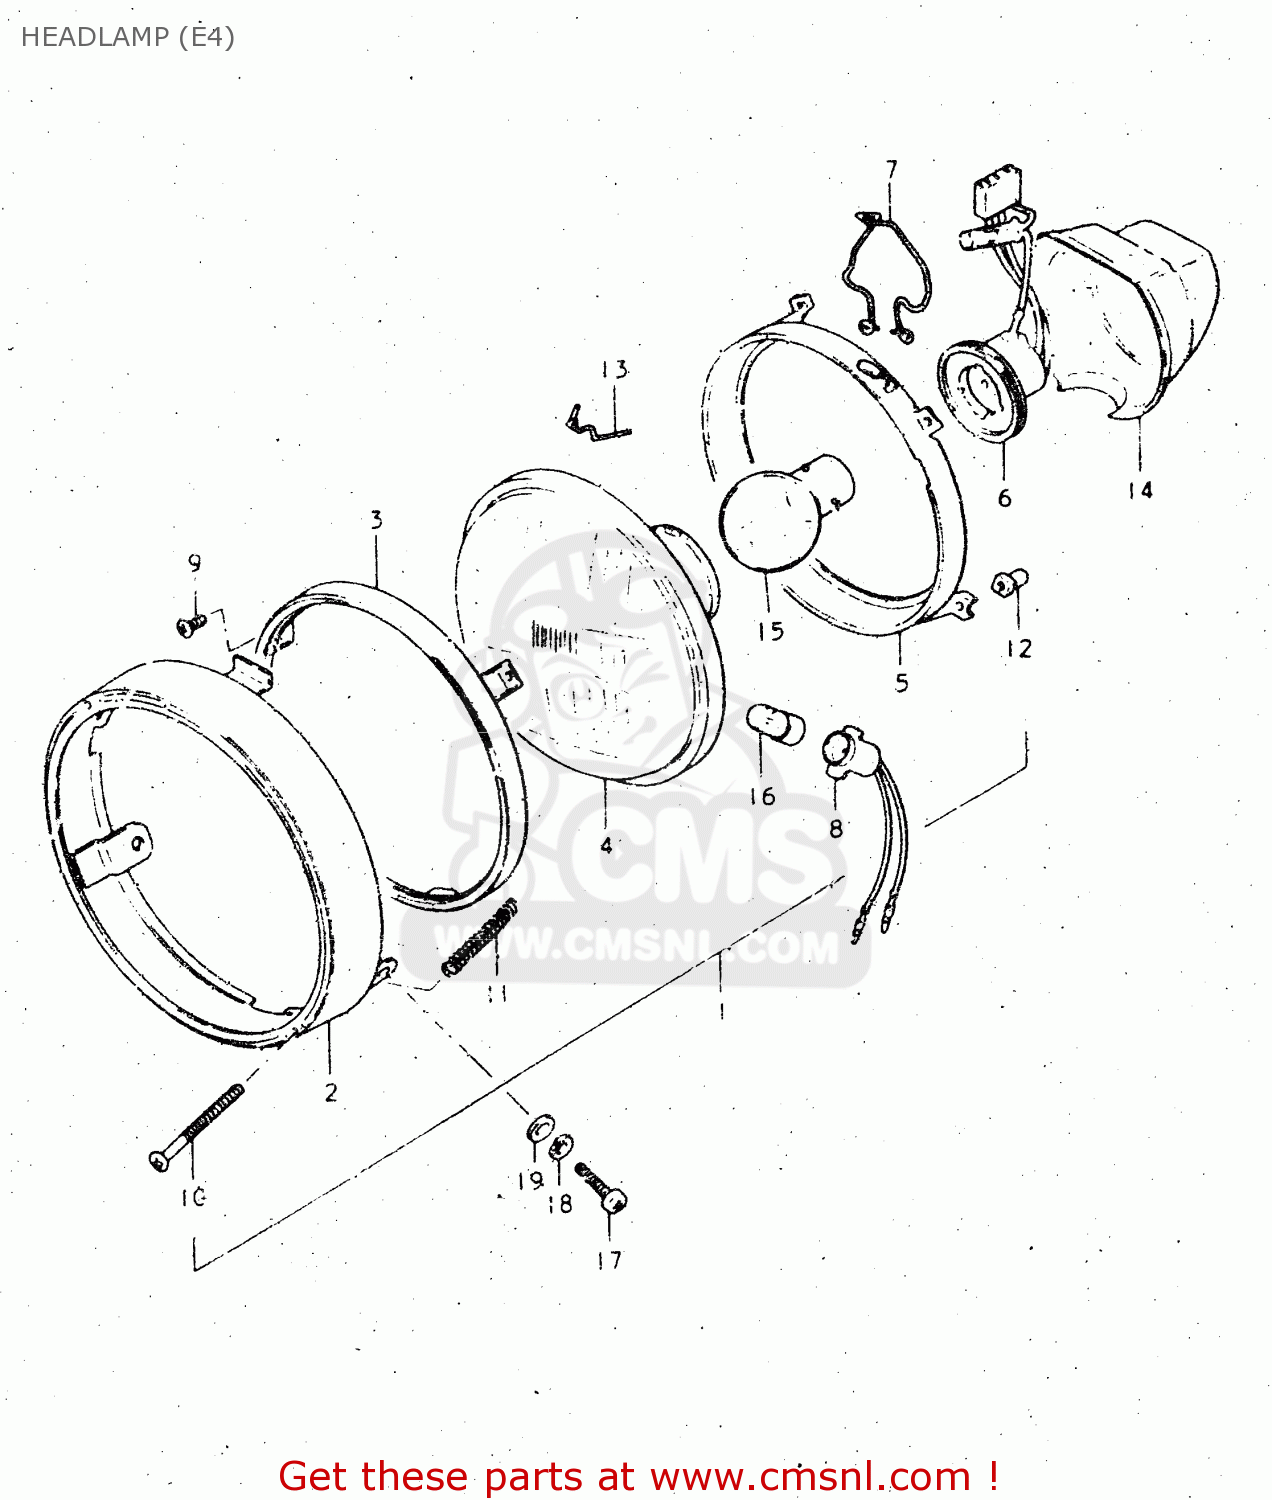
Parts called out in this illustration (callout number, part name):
1	HEADLAMP ASSY
2	RIM
3	RETAINER,HEADLAMP
4	UNIT
5	RING, MOUNTING
6	SOCKET
7	CLAMP,HEADLAMP
8	SOCKET
9	SCREW
10	SCREW,HEADLAMP ADJUST
11	SPRING,ADJUSTING
12	NUT,HEADLAMP ADJUSTER
13	SPRING,HEADLAMP UNIT
14	COVER, SOCKET
15	BULB (6V,36/36W)
16	BULB (6V,4W)
17	SCREW
18	LOCK WASHER
19	WASHER
